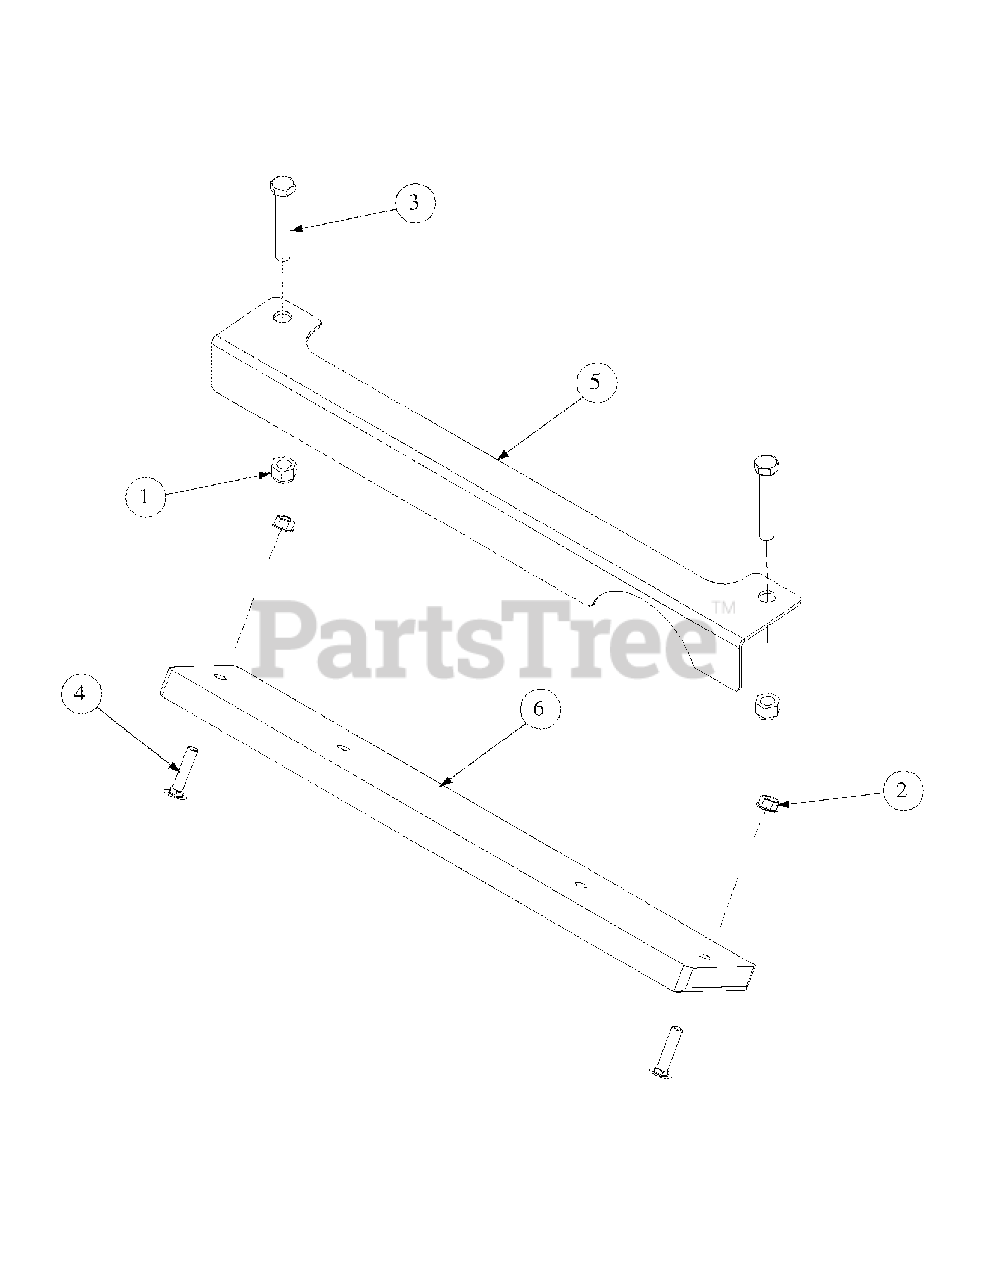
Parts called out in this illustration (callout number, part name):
1	Hex Nut, 1/2-13, Insert Lock
2	Nut, Hex 3/8-16 Flange Lock
3	HHCS, 1/2-13, 3.00
4	Carriage Bolt, 3/8-16 x 1.75
5	Rear Bumper Bracket
6	Bar Weight
